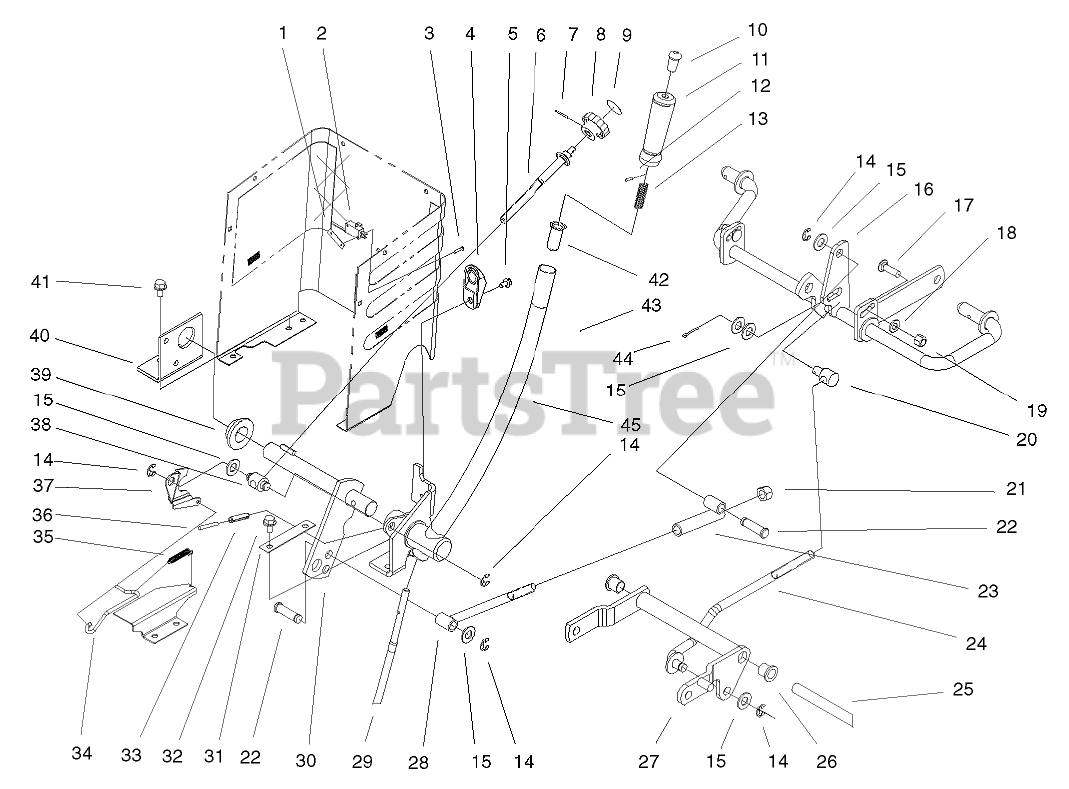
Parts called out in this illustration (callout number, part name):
1	NUT-SPEED
2	SWITCH-MICRO
3	SCREW-PPHTF
4	WEDGE - HOC
5	SCREW-HWH
6	ROD - HOC
7	PIN-SPIROL
9	DECAL-HEIGHT KNOB
10	TIP-ROD
11	GRIP-HANDLE
12	PIN-SPIROL
13	SPRING-COMPRESSION
14	RING-RETAINING, EXTERNAL
15	WASHER-FLAT
16	SHAFT-GAGE
17	BOLT-CARR
18	WASHER-FLAT
19	NUT-LOCK, NI
20	ROD-TRUNNION LIFT
21	NUT-LOCK, NI
25	SHAFT-PIVOT, PEDAL
26	BUSHING-FLANGE
27	ARM-PIVOT
29	ROD-LEVER, LIFT
30	SHAFT-LIFT
32	SCREW-HWHTF
33	PIN-ROLL
34	ROD - HOC INDICATOR
35	SPRING - EXTENSION
36	PIN-SPRING
37	PLATE - HOC GAGE
38	TRUNNION
39	BEARING-FLANGE
40	BRACKET-PIVOT, LINKAGE
41	SCREW-HWHTF
42	RETAINER-SPRING
43	DECAL-LIFT
44	PIN-COTTER
45	LEVER-LIFT
